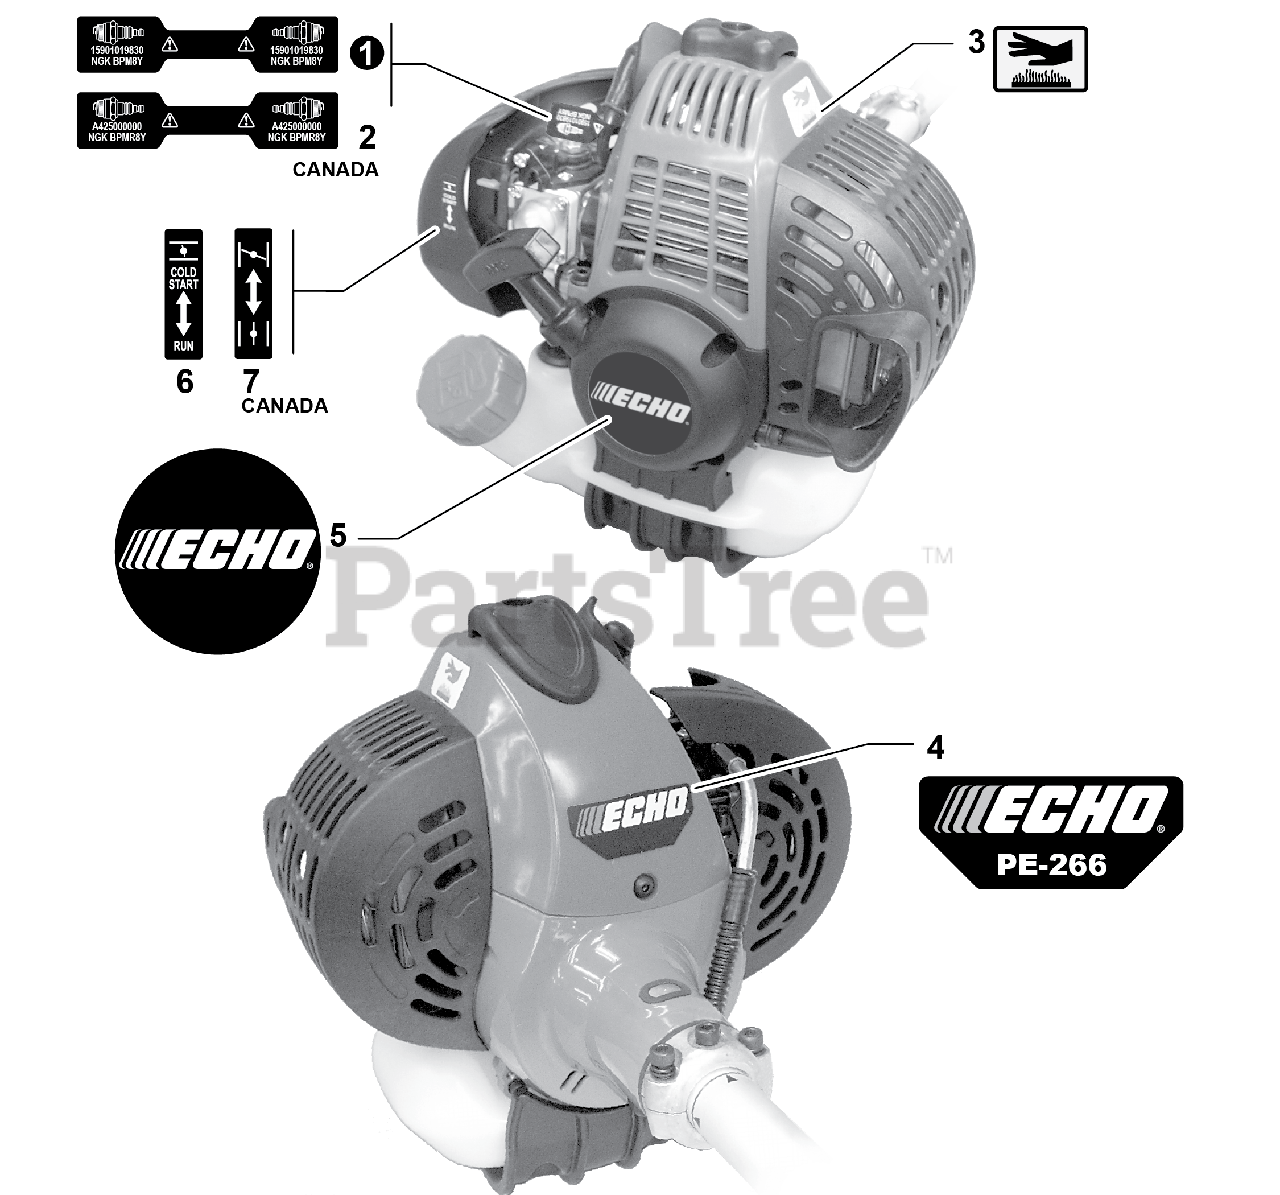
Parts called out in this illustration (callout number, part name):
1	LABEL, SPARK PLUG - BPM8Y
2	LABEL, SPARK PLUG - BPMR8Y
3	LABEL, CAUTION - HOT
4	LABEL - MODEL PE-266
5	LABEL, ECHO
6	LABEL, CHOKE
7	LABEL, CHOKE
